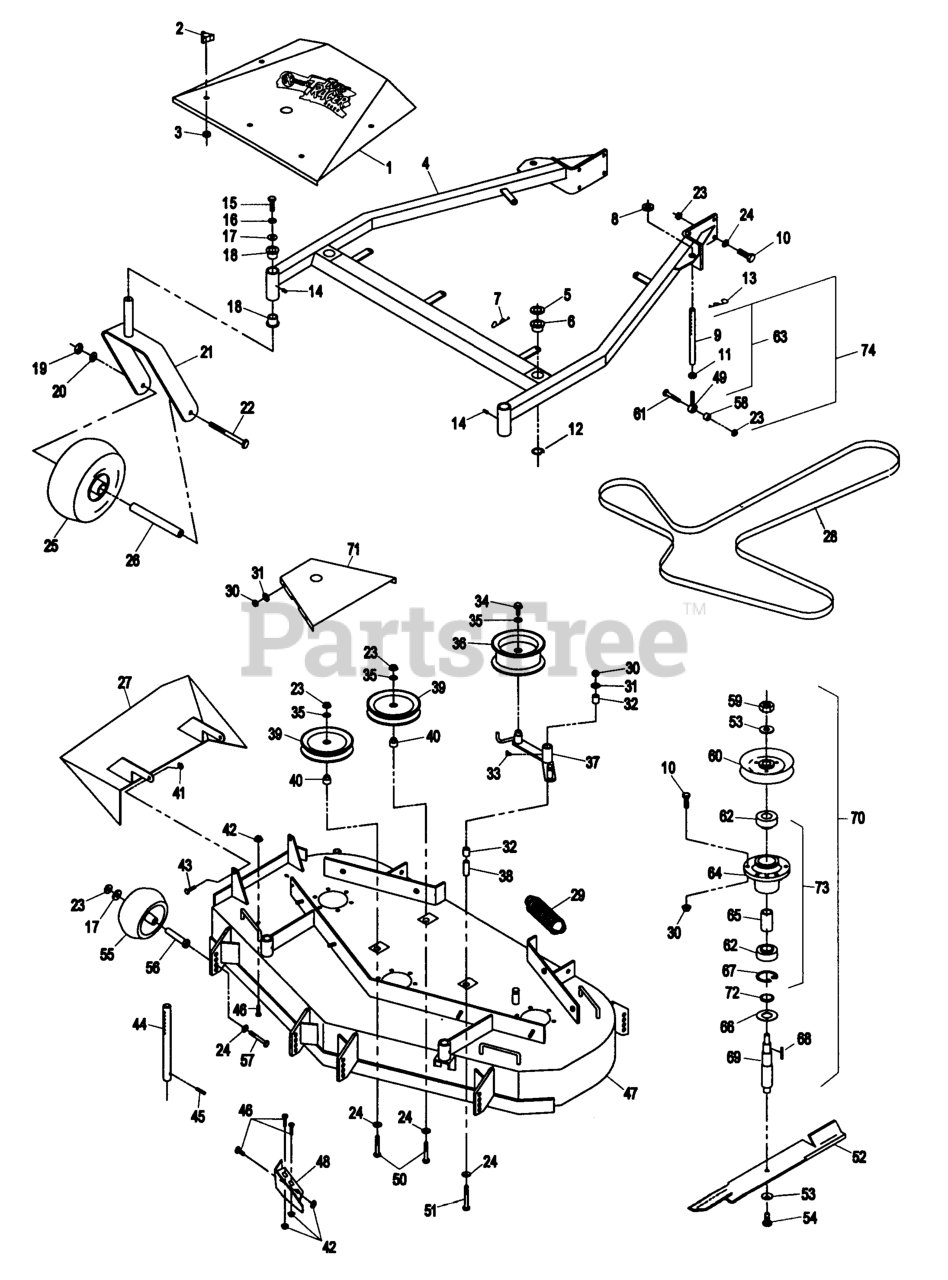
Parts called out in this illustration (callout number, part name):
2	KNOB-3 PRONG
4	SUPPORT,DECK W/BUSHINGS
5	SPACER-DECK SUPPORT
6	BUSHING-DECK
9	LINK, DECK SUPPORT
13	PIN,HAIR COTTER
18	BEARING-FLANGED
27	WLD,CHUTE DISCHARGE
28	BELT,DECK DRIVE
32	SLEEVE-BEARING
38	BUSHING-PIVOT, IDLER
39	PULLEY-IDLER
40	BUSHING-IDLER
44	ROD,DECK SUPPORT
47	ASM,DECK W/DECALS TTHP52
48	WLD,BAFFLE DISCHARGE
49	BALLJOINT
51	SCREW-HH
53	WASHER-SPRING
55	ROLLER-SCALP, ANTI
56	BUSHING-ROLLER
60	SHEAVE,W/HUB 5.72
62	BEARING
65	SPACER-BEARING
66	GUARD-BEARING, BOTTOM
68	KEY-RECTANGLE
69	SHAFT,SPINDLE
70	HOUSING,CUTTER COMPLETE
72	SPACER-PULLEY/BEARING
74	Uknown
